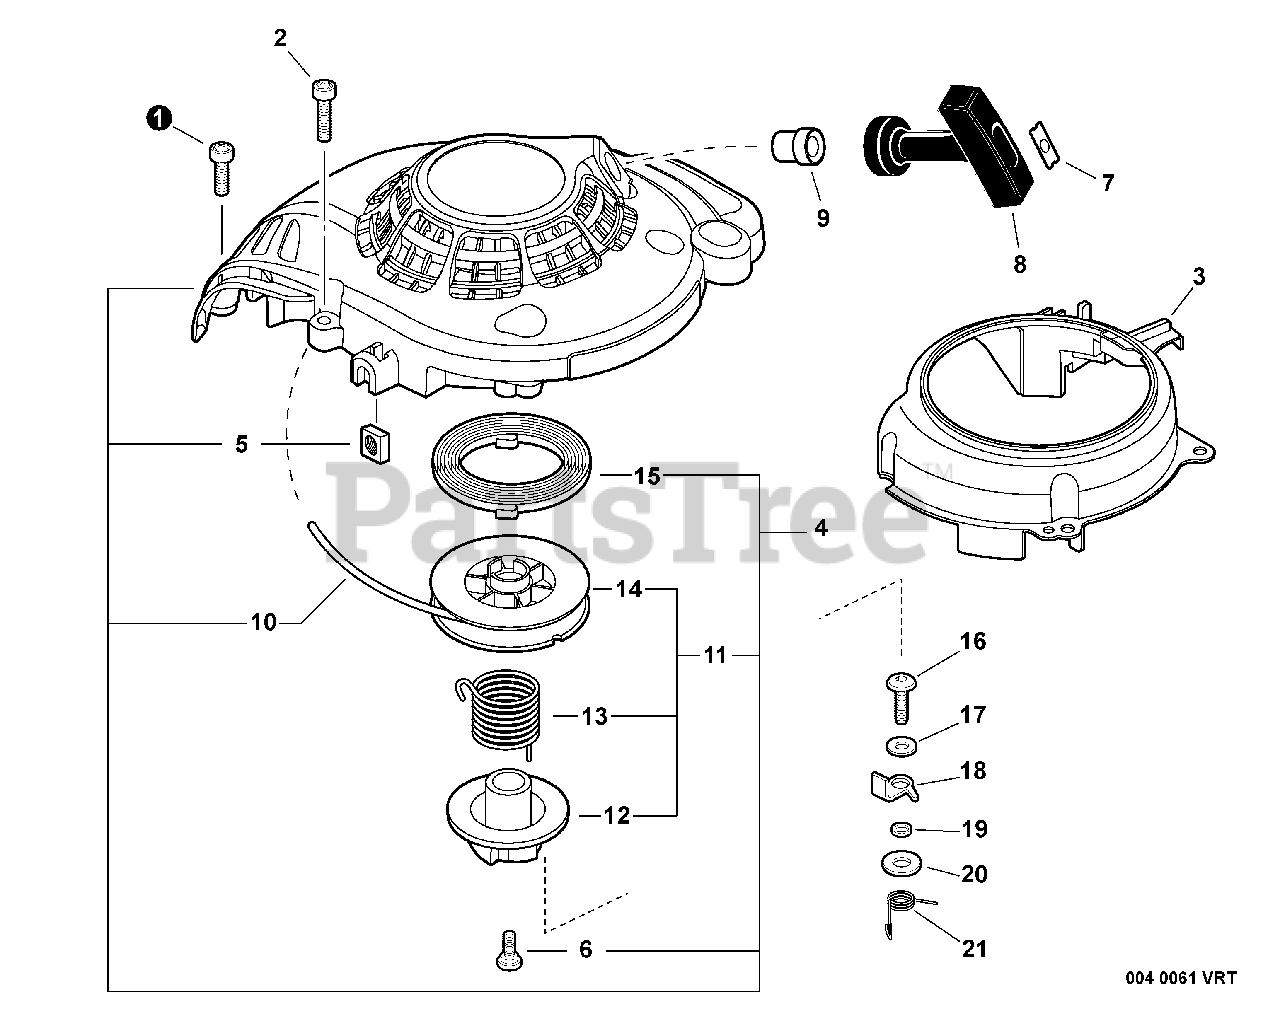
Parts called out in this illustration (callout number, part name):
1	BOLT, TORX 4×12
2	BOLT, TORX 4×16
3	COVER, FAN
4	STARTER ASSY, RECOIL
5	NUT M5
6	SCREW
7	RETAINER, ROPE
8	GRIP, STARTER
9	GUIDE, ROPE
10	ROPE, STARTER
11	REEL/CAM PLATE SET
12	PAWL CATCHER
13	SPRING, TORSION
14	REEL, ROPE
15	SPRING, RECOIL
16	BOLT 5×14
17	WASHER 5.5×12×0.8
20	WASHER 5.5×16×0.8
21	SPRING, TORSION
